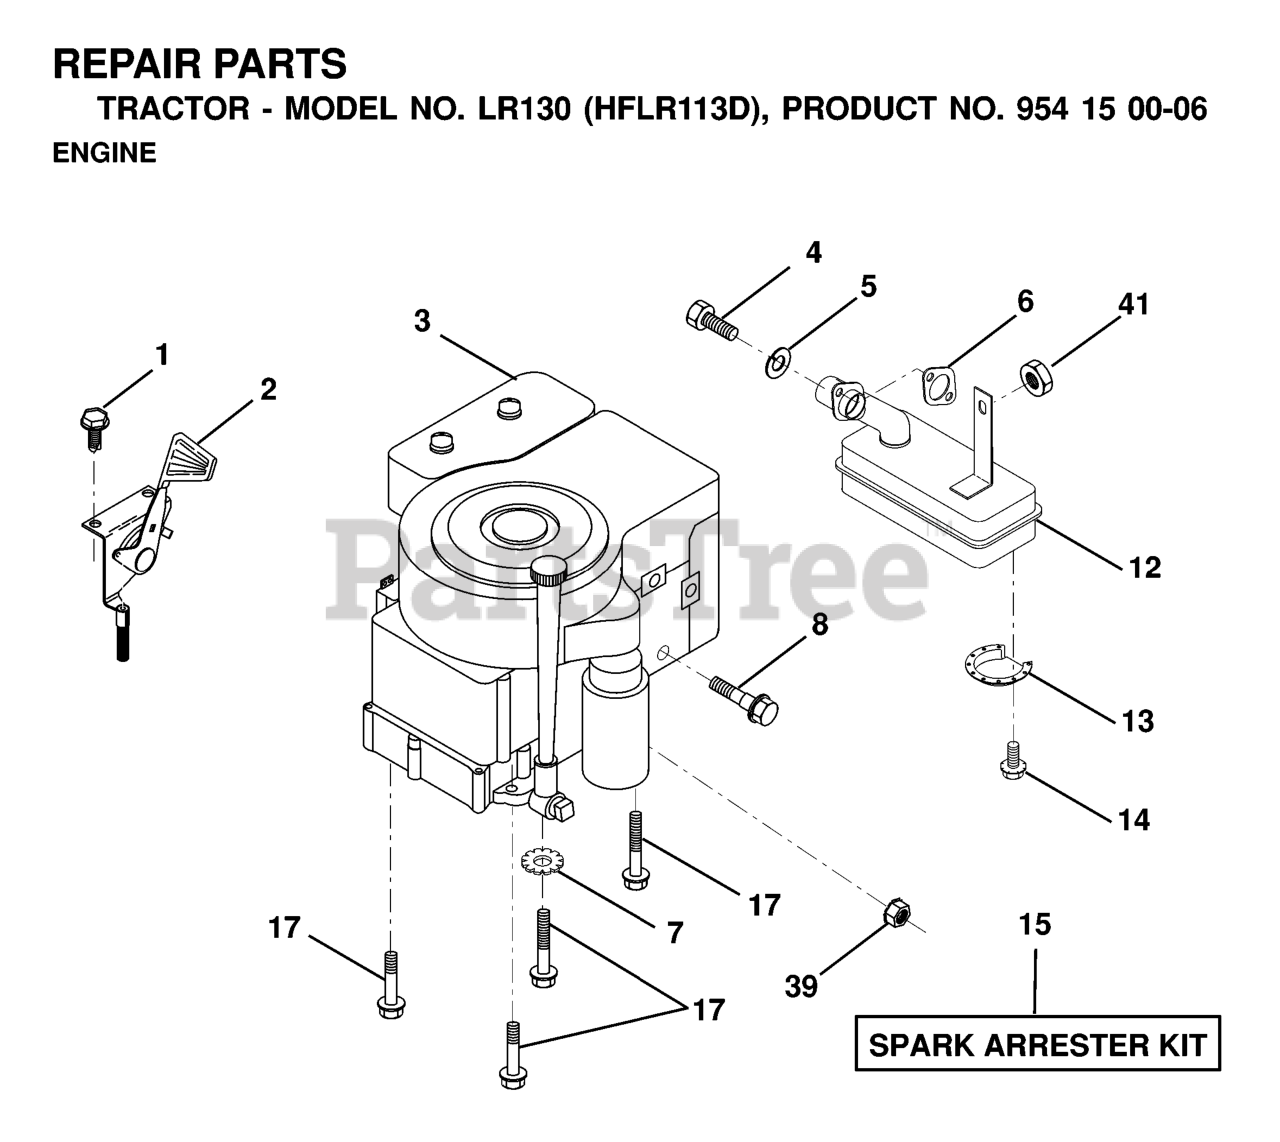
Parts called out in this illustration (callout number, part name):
1	SCREW LT
2	CONTROL.TH/CH.RH.BLK.FLG.26
5	WASHER.LOCK.HVY.HLCL.SPR.5/16
6	REPL BY 532 27 22-93
7	LOCKWASHER
8	SHOULDER BOLT ST
13	DEFL MUFFLER LTV
14	SCREW
15	KIT.SPARK ARRESTOR 794945 B&S
17	SCREW LT
39	NUT FLANGE 1/4-20 STARTER NUT
41	NUT LOCK HEX FLANGE 5/16-18
